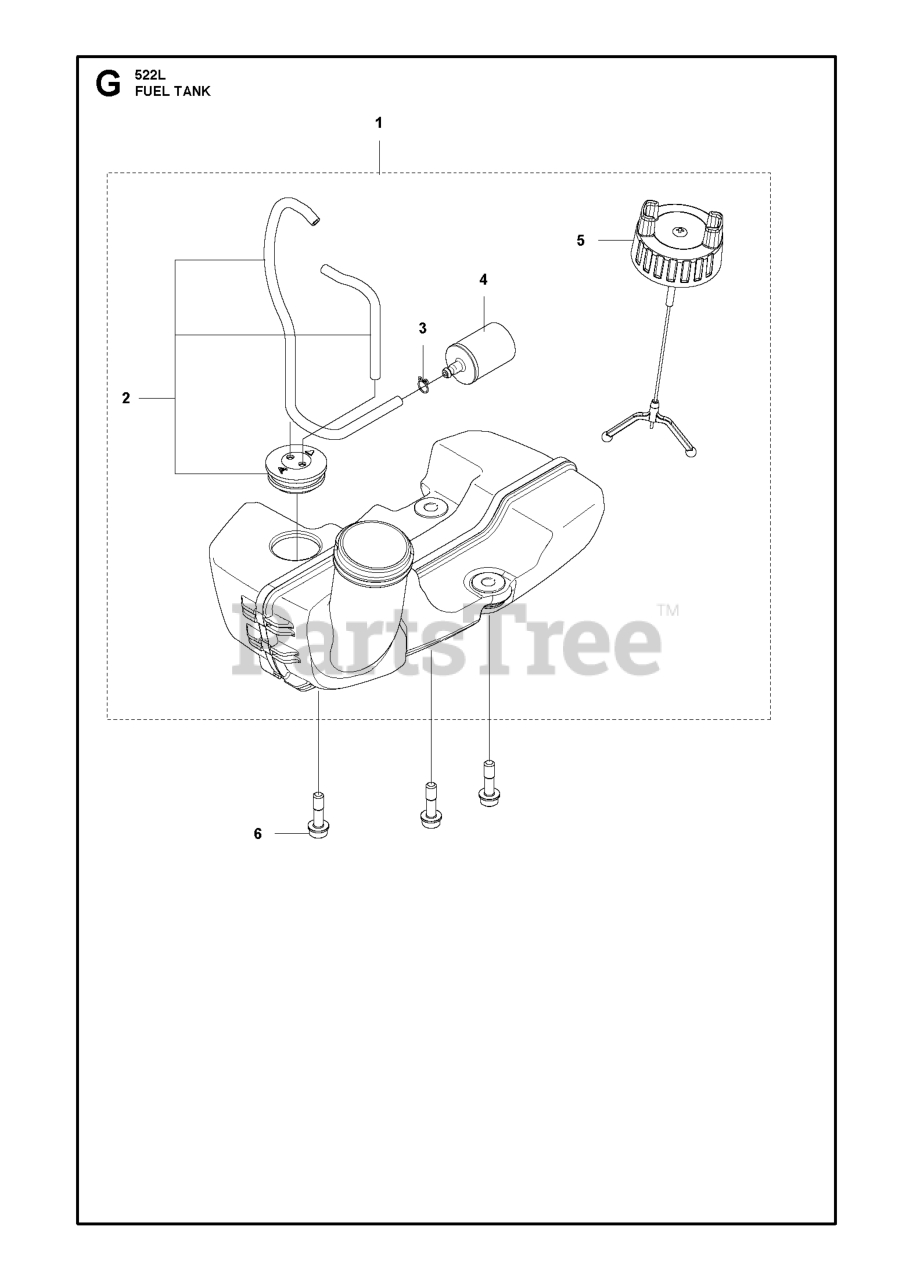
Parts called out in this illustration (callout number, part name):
2	HOSE ASSY
4	RP FUEL FILTER
5	TANK CAP COMP
6	BOLT
